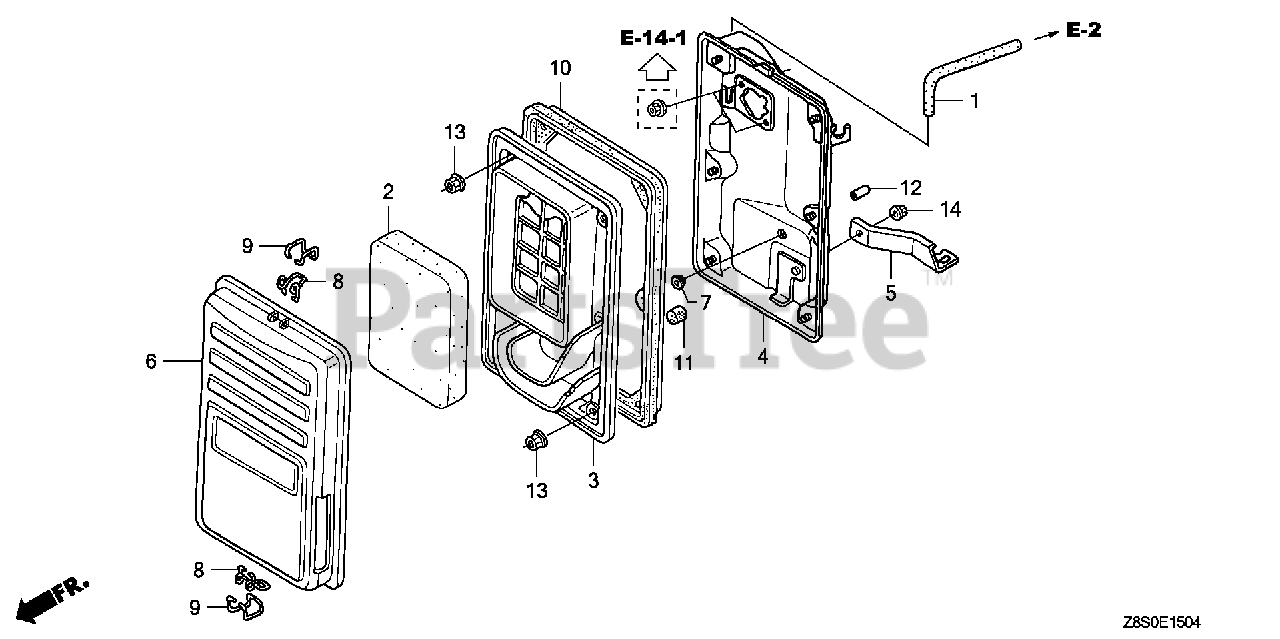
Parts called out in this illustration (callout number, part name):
1	TUBE, BREATHER
2	ELEMENT, AIR CLEANER
3	SEPARATOR, AIR CLEANER
4	HOUSING, AIR CLEANER
5	STAY, AIR CLEANER
6	COVER, AIR CLEANER
7	GROMMET, AIR CLEANER
8	CLIP A, AIR CLEANER WIRE
9	CLIP B, AIR CLEANER WIRE
10	SEAL, AIR CLEANER
11	FILTER, DRAIN TUBE
12	CAP, SEALING
13	NUT, FLANGE (5MM)
14	NUT, FLANGE (6MM)
